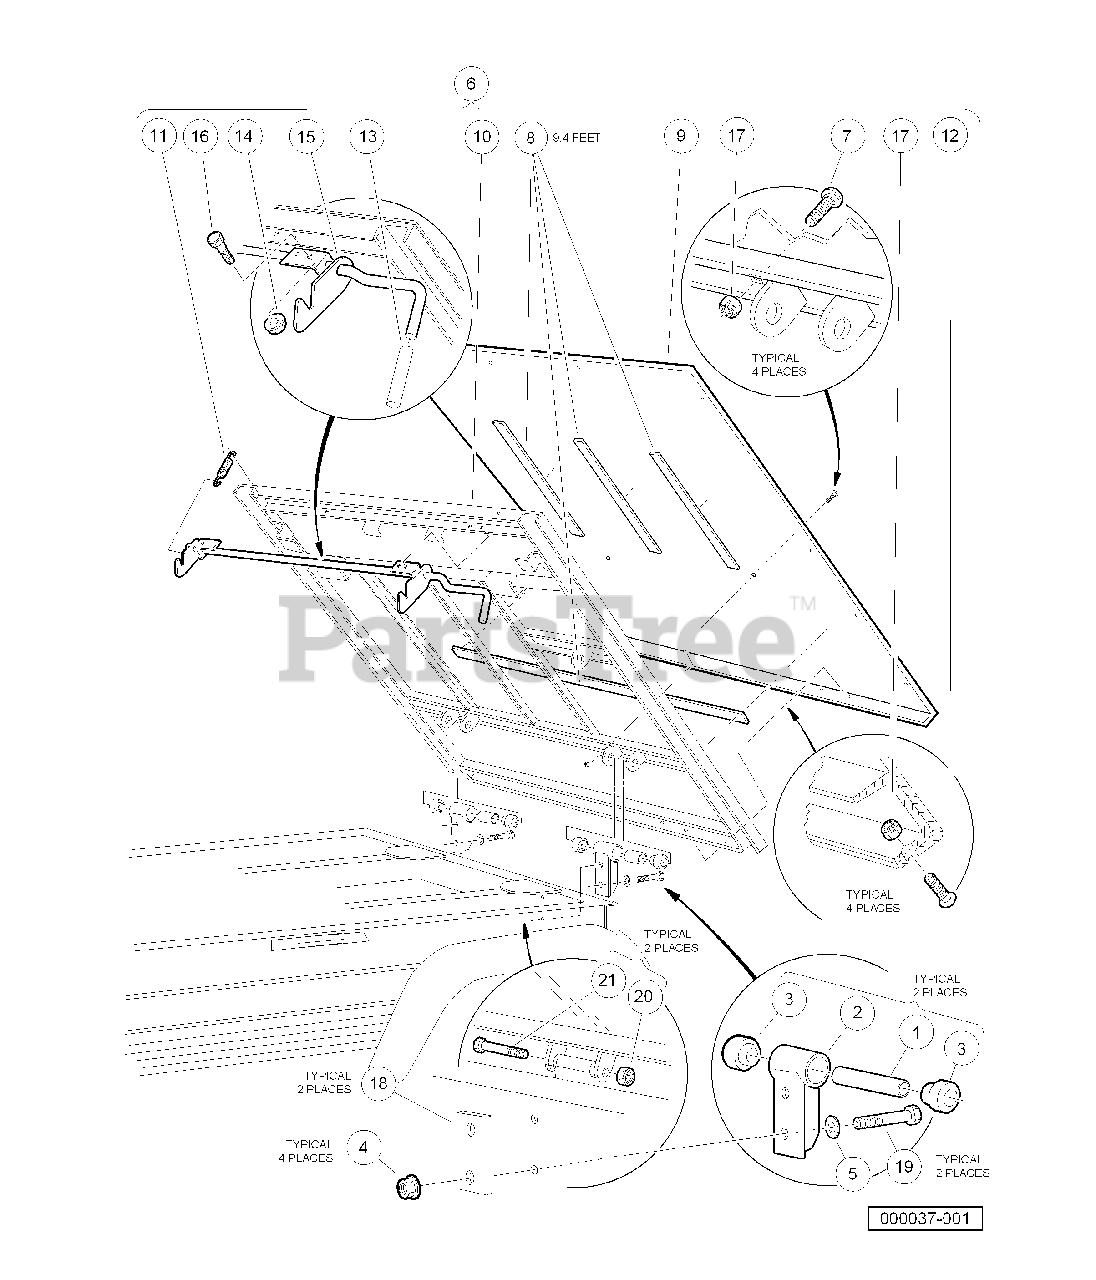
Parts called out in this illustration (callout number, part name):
1	Bushing, Steel
3	Bushing, Urethane
4	Locknut, 3/8-16 Flanged Dimple
5	Washer, 3/8 Type B Hard Flat
6	Tilt Bed Assembly
7	Bolt, Carriage, 5/16-18 X 1.00
8	Tape, Vinyl Foam 1/8" x 3/4"
9	Plate, Floor Bed
10	Frame Assembly
11	Extension, Spring Latch
12	Screw, 5/16-18 X 0.88 Torx Truss-Head
13	Grip, Tilt Latch Hand
14	Locknut, 1/4-20 Hex Whiz
15	Ltch Weld Asm Tlt Bd
16	Screw, 1/4-20 X 0.625 Hex-Head Cap
17	Locknut, 5/16-18 Nylon Insert
18	Plate, Back
19	Bolt, 3/8-16 X 3.00 Hex Head
20	Locknut, 3/8-16 Hex
21	Screw, 3/8-16 X 3.375 Hex Cap
